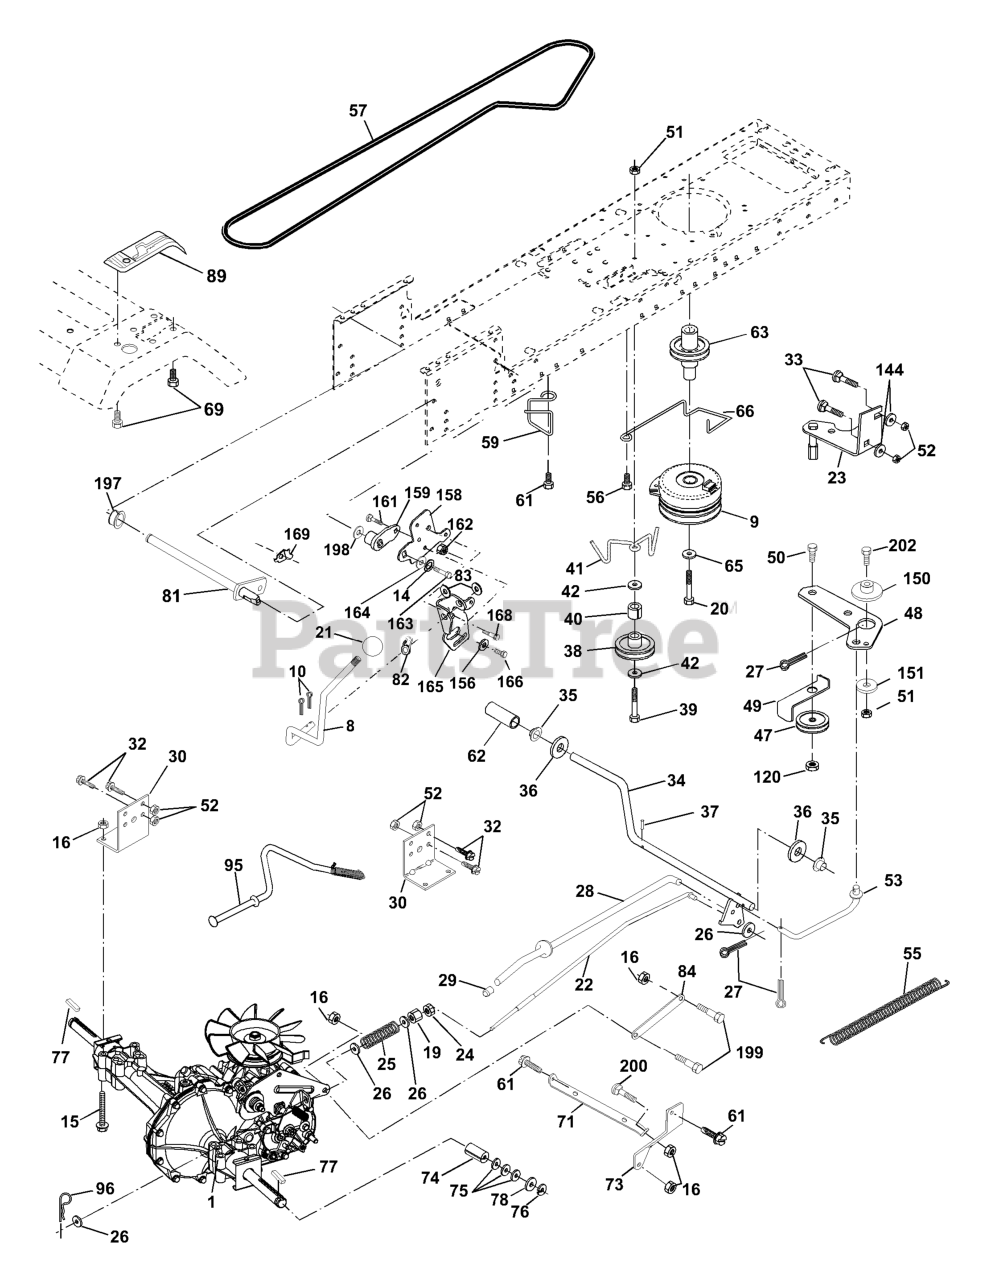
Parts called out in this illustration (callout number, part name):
8	ROD.SHIFT.FENDER.ADJ.LT.CRD
9	CLUTCH.ELECT.EVX.
10	PIN COTTER
14	LOCKWASHER
15	BOLT HEX 5/16-18 GR 5
16	NUT.71038.31-18.HEX.NYLOCK
19	NUT
20	BOLT HEX
21	KNOB.DELUXE.(PISTOL.GRIP).BLAC
22	ROD BRAKE HYDRO
24	NUT
25	SPRING ROD LT
26	WASHER
27	COTTER PIN
28	ROD, PARKING BRAKE
29	PLUNGER CAP
30	BRKT, TRNSXLE MNT 20"
32	BOLT
33	RP BOLT 5/16-18 X3/4 ZN/YEL GR
34	SHAFT, FOOT PEDAL
35	BEARING.NYLON
36	WASHER LT
37	DRIVE PIN
38	PULLEY.FLAT
39	BOLT
40	SPACER, SPLIT
41	KEEPER, BELT IDLER
42	WASHER
47	IDLER PULLEY
48	BELLCRANK, CLUTCH
49	RETAIN BELT
50	BOLT
52	LOCKNUT
53	LINK, CLUTCH LT
55	SPRING, RETURN LT
56	SCREW THDROL 3/8-16 X 1-1/2
57	DRIVE BELT, LTH & YTH TRACTORS
59	KEEPER, BELT CENTER
61	SCREW 3/8-16X3/4
62	PEDAL COVER T
63	PULLEY, ENGINE
65	LOCKWASHER
66	KEEPER BELT ENGINE
69	SCREW.HI-LO.CONSOLE
71	STRAP TORQUE LH HYDRO
73	STRAP TORQUE RH HYDRO
74	SPACER AXLE
77	SQUARE KEY
81	SHAFT ASM CROSS TAPERED
82	SPRING,TORSION
83	WASHER
84	LINK TRANSAXLE
89	CONSOLE, SHIFT
95	CONTROL ASM. BYPASS HYDRO
96	RETAINER M
120	NUT LOCK FLG 3/8-16 UNC
144	Washer 11/32 x 5/8 x 16 Ga.
150	SPACER, RETAINER
151	WASHER 12/32X2X10GA
156	WASHER.SRRTD.5/16
158	BRACKET
159	HUB
161	BOLT
162	NUT.CROWNLOCK.1/4
163	BOLT
164	Washer 5/8 x .281 x 10 Ga.
165	RP BRACKET
168	BOLT.SHOULDER.5/16-18X
169	PLATE.FASTENING.CROSS.SHAFT
197	NYLINER SNAP 5/8" ID
198	WASHER.NYL.7/8IDX.105"HYD CR
199	BOLT SHOULDER 5/16-18 UNC
200	BOLT
202	BOLT.3/8-16X1.50
